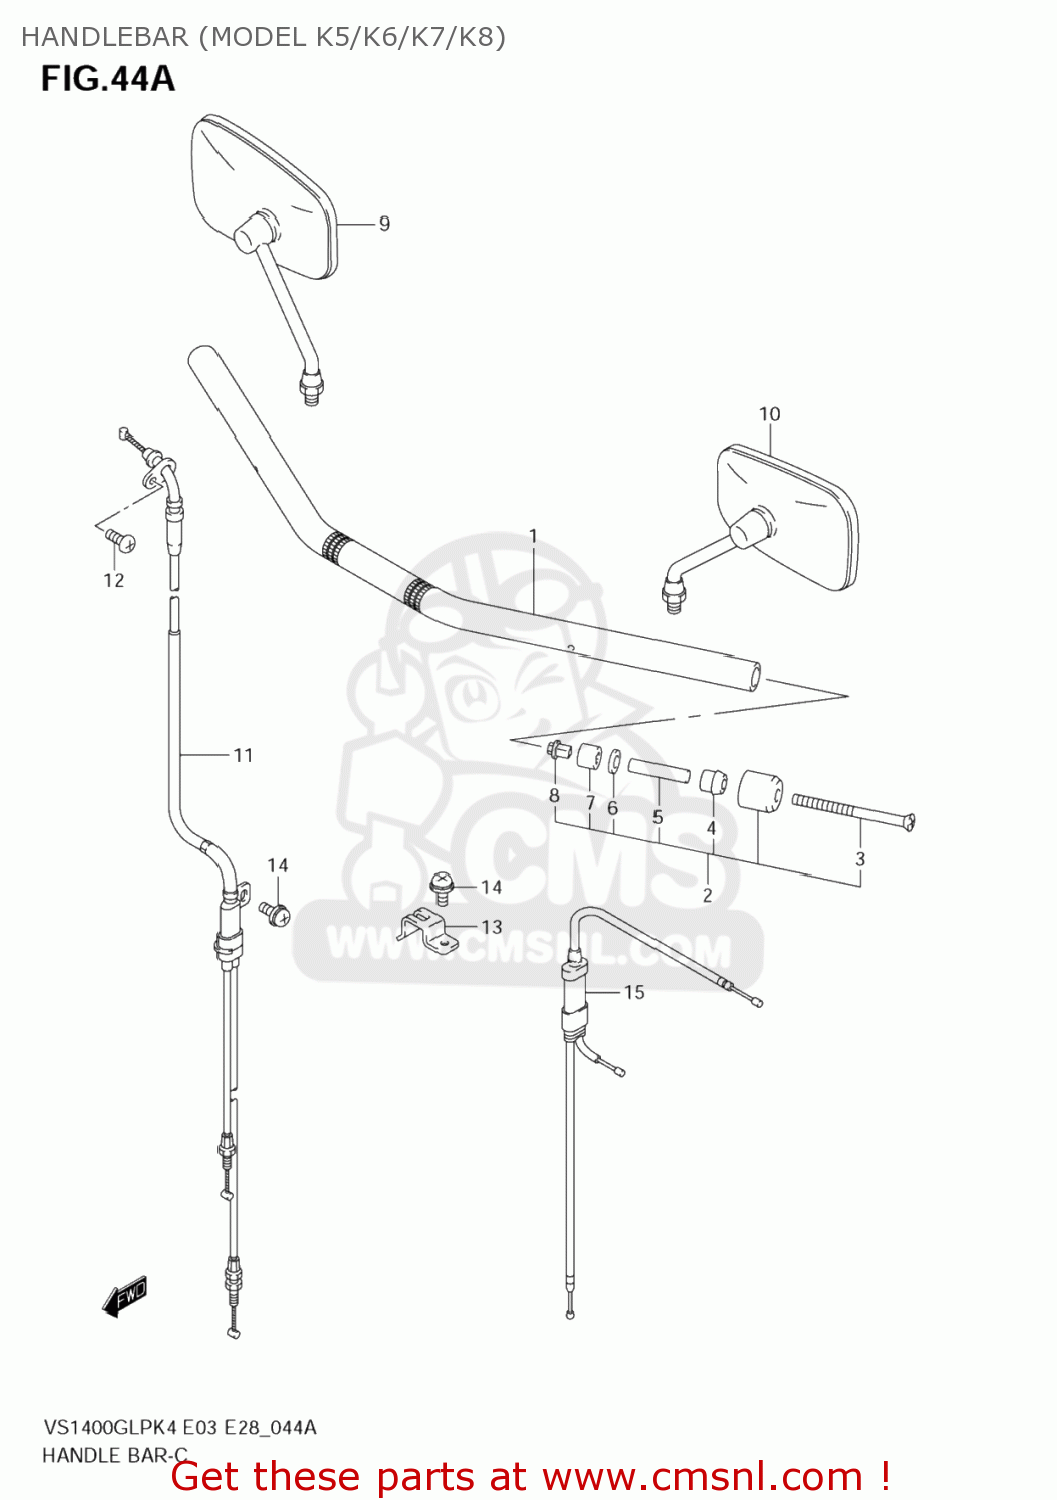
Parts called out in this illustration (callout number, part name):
1	HANDLEBAR
2	BALANCER SET,HANDLEBAR
3	SCREW(6X127)
4	EXPANDER,HANDLE BALANCER NO.2
5	SPACER,EXPANDER
6	WASHER(6.5X16X4)
7	EXPANDER,HANDLE BALANCER
8	NUT,HANDLE BALANCER
9	MIRROR ASSY,RR VIEW,R
10	MIRROR ASSY,RR VIEW,L
11	CABLE ASSY,THROTTLE
12	SCREW(5X10)
13	CLAMP,THROTTLE CABLE CONNECTOR
14	SCREW
15	CABLE ASSY,STARTER
